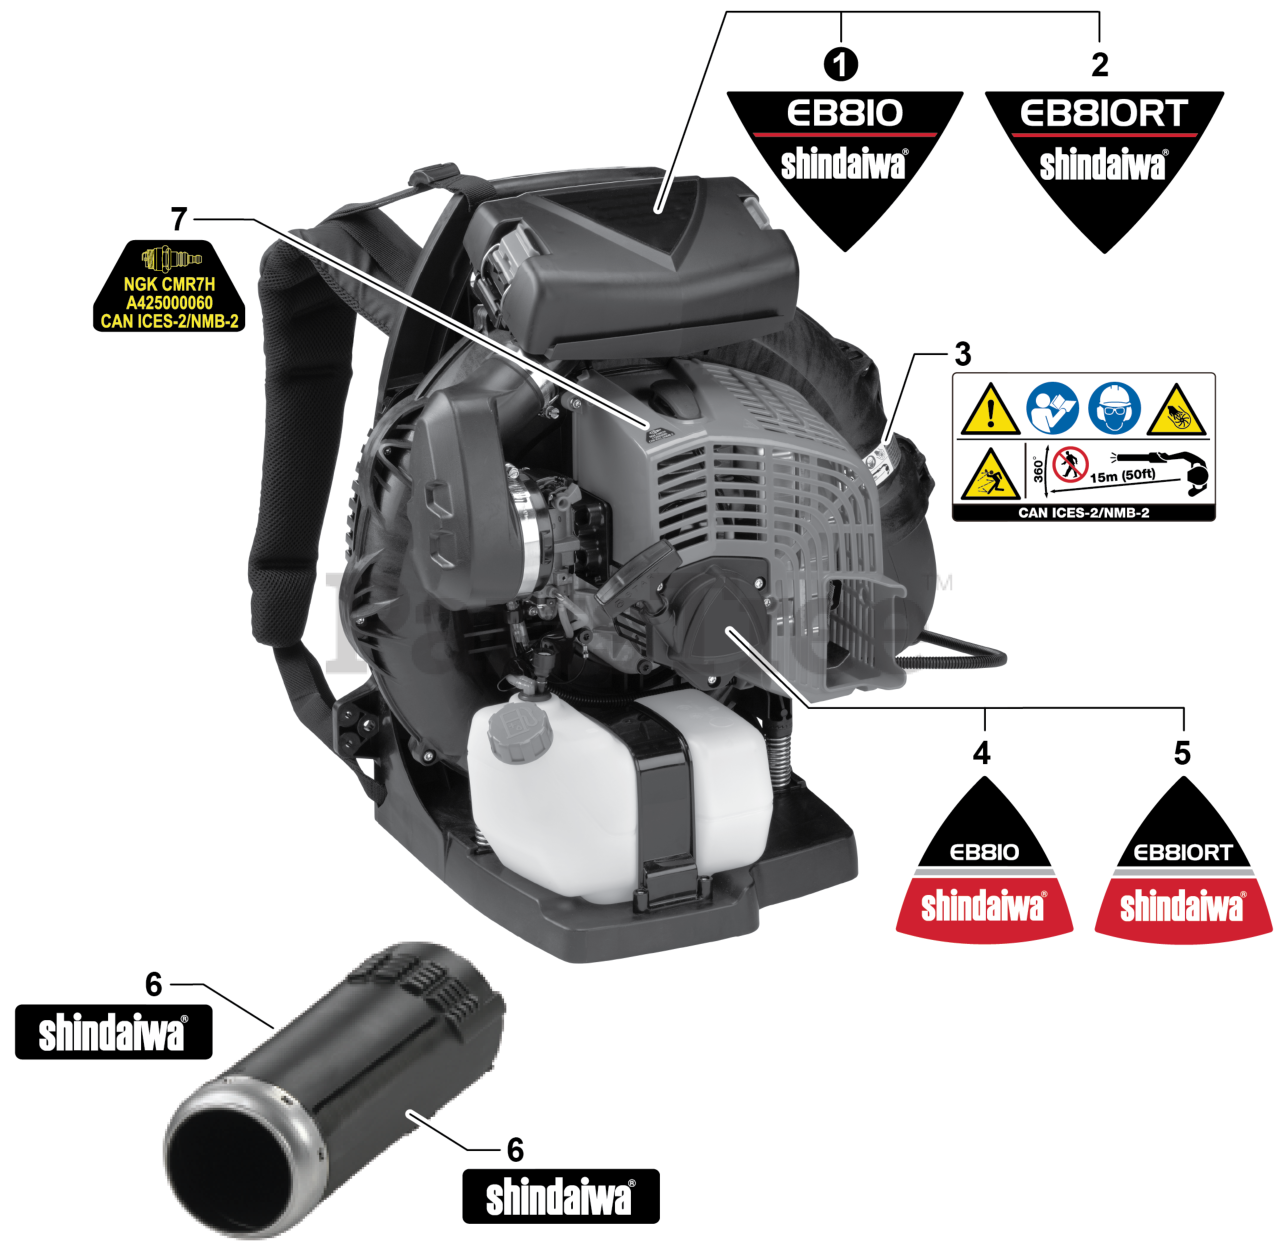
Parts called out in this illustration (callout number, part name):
1	LABEL - EB810
2	LABEL - EB810RT
3	LABEL - CAUTION
4	LABEL - RECOIL STARTER - EB810
5	LABEL - RECOIL STARTER - EB810RT
6	LABEL - SHINDAIWA BLOWER TUBE
7	LABEL - SPARK PLUG - CMR7H
